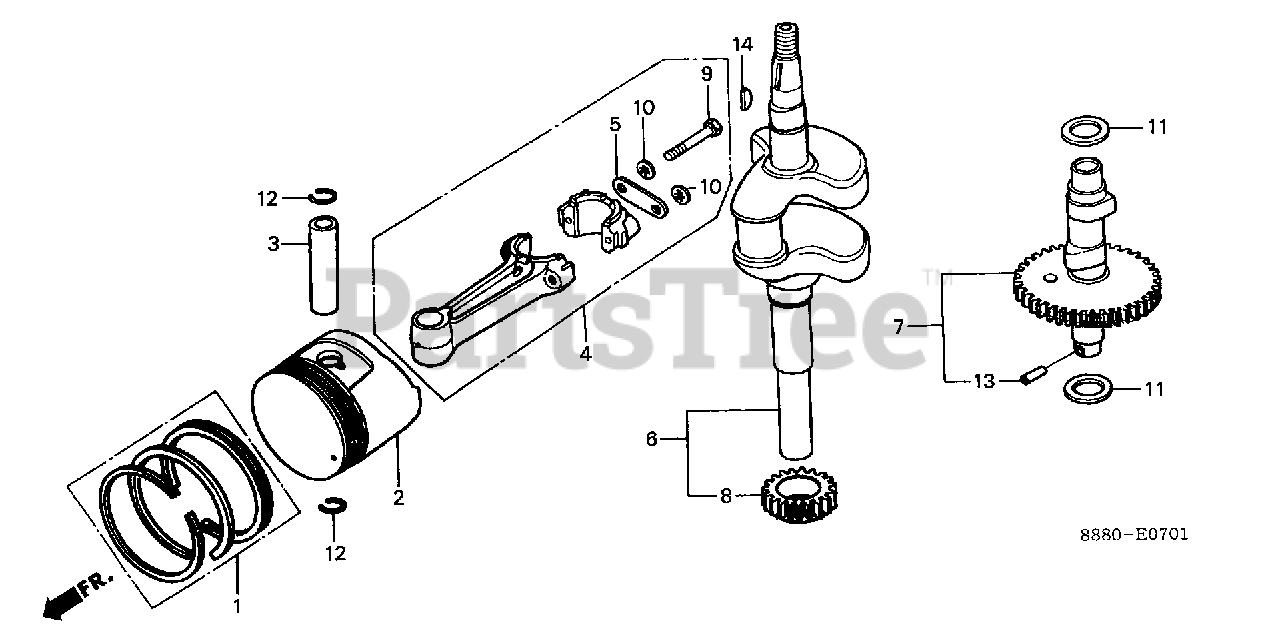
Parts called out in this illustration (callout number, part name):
1	RING SET, PISTON (STD)
1	RING SET, PISTON (0.25)
1	RING SET, PISTON (0.50)
1	RING SET, PISTON (0.75)
2	PISTON (STD)
2	PISTON (0.25)
2	PISTON (0.50)
2	PISTON (0.75)
3	PIN, PISTON
4	ROD ASSY., CONNECTING
5	WASHER, CONNECTING ROD
6	CRANKSHAFT
7	CAMSHAFT ASSY.
8	GEAR, TIMING
9	BOLT, CONNECTING ROD (7MM)
10	WASHER, LOCK (7MM)
11	WASHER, THRUST (18MM)
12	CLIP, PISTON PIN (15MM)
13	PIN, SPRING (2.5X16)
14	KEY, SPECIAL WOODRUFF (25X18)
